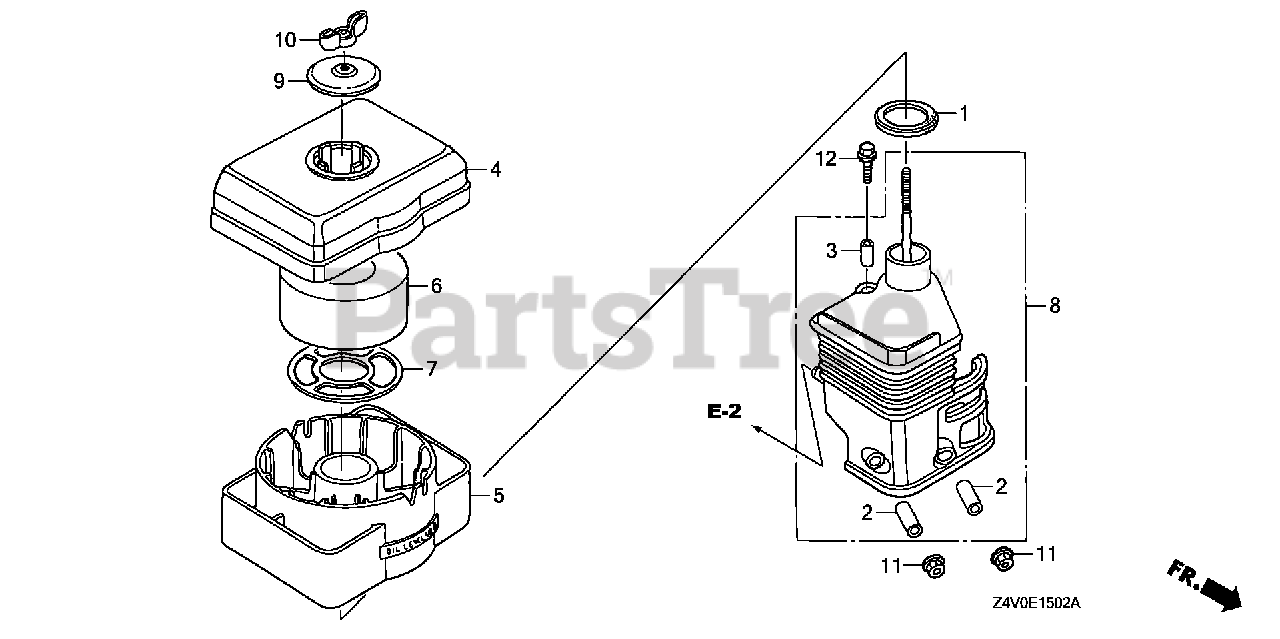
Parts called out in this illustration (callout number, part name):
1	GASKET, ELBOW
2	COLLAR, AIR CLEANER
3	COLLAR B, AIR CLEANER
4	BODY, CLEANER (OIL BATH)
5	PAN, CLEANER OIL (OIL BATH)
6	ELEMENT, AIR CLEANER (OIL BATH)
7	GRID, AIR CLEANER
8	ELBOW, AIR CLEANER
9	CAP, CLEANER
10	NUT, TOOL BOX SETTING
11	NUT, FLANGE (6MM)
12	BOLT, FLANGE (6X20)
